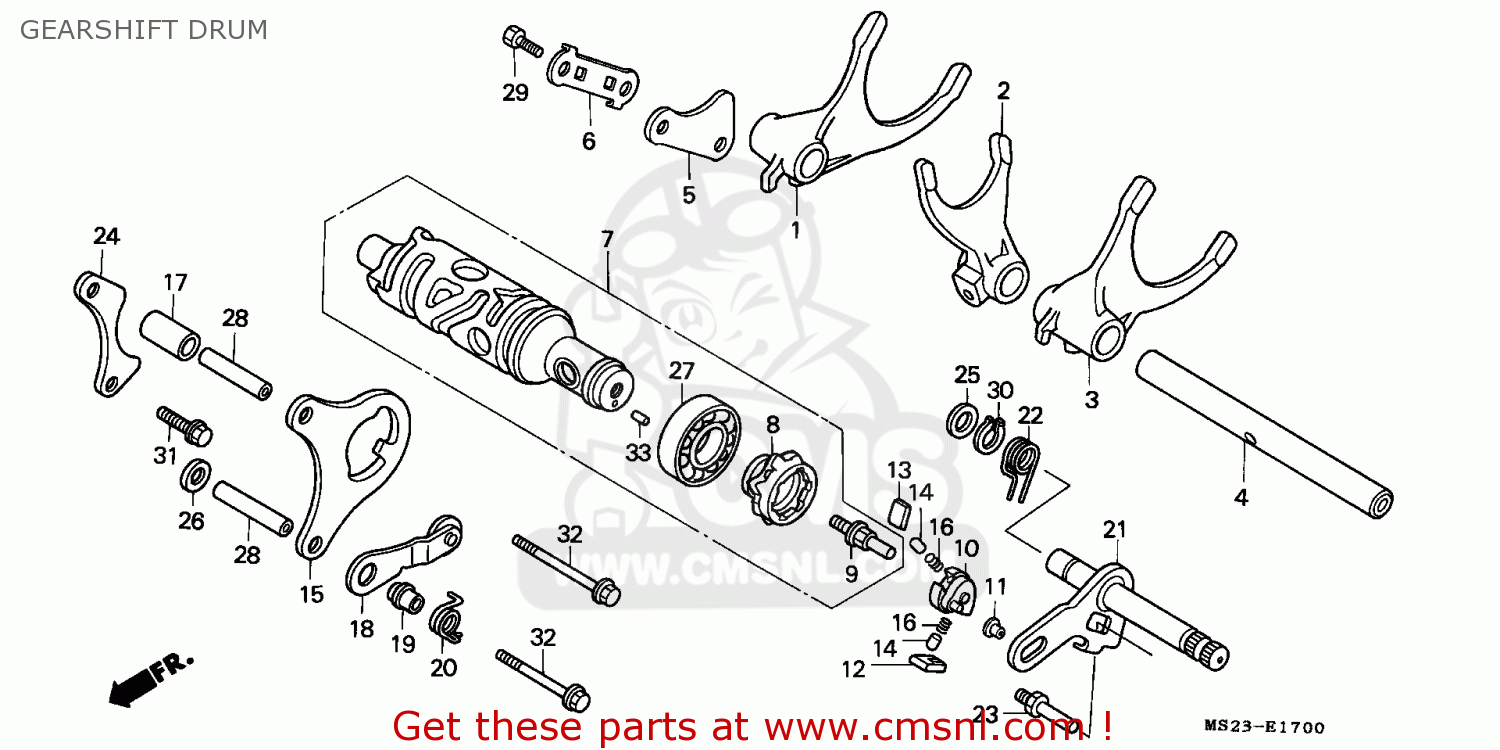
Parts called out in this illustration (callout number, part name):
1	FORK R,GEAR SHIFT
2	FORK C,GEAR SHIFT
3	FORK L,GEAR SHIFT
4	SHAFT,GEAR SHIFT
5	STOPPER,GEARSHIFT
6	PLATE,LOCK
7	DRUM COMP.,GEARSH
8	CENTER,GEARSHIFT
9	PIN.SHIFTER
10	SHIFTER,DRUM
11	COLLAR,DRUN SHIFT
12	PAWL A,RATCHET
13	PAWL B,RATCHET
14	PLUNGER,PAWL
15	PLATE,GUIDE
16	SPG PAWL PLUNGER
17	COLLAR,GUIDE PLAT
18	STOPPER COMP,DRUM
19	COLLAR,DRUM STOPP
20	SPG DRUM STOPPER
21	SPINDLE COMP.,GEA
22	SPRING,SHIFT RETU
23	PIN, SHIFT RETURN
24	PLATE,SHIFT DRUM
25	WASHER,THRUST 14
26	WASHER 8MM
27	B/BRG RAD N/COM
28	PIN DOWEL 8X31.5
29	BOLT,HEX.,6X14
30	CIRCLIP,EX,14
31	BOLT,FLANGE 6X14
32	BOLT,FLANGE,6X45
33	ROLLER,4X8
